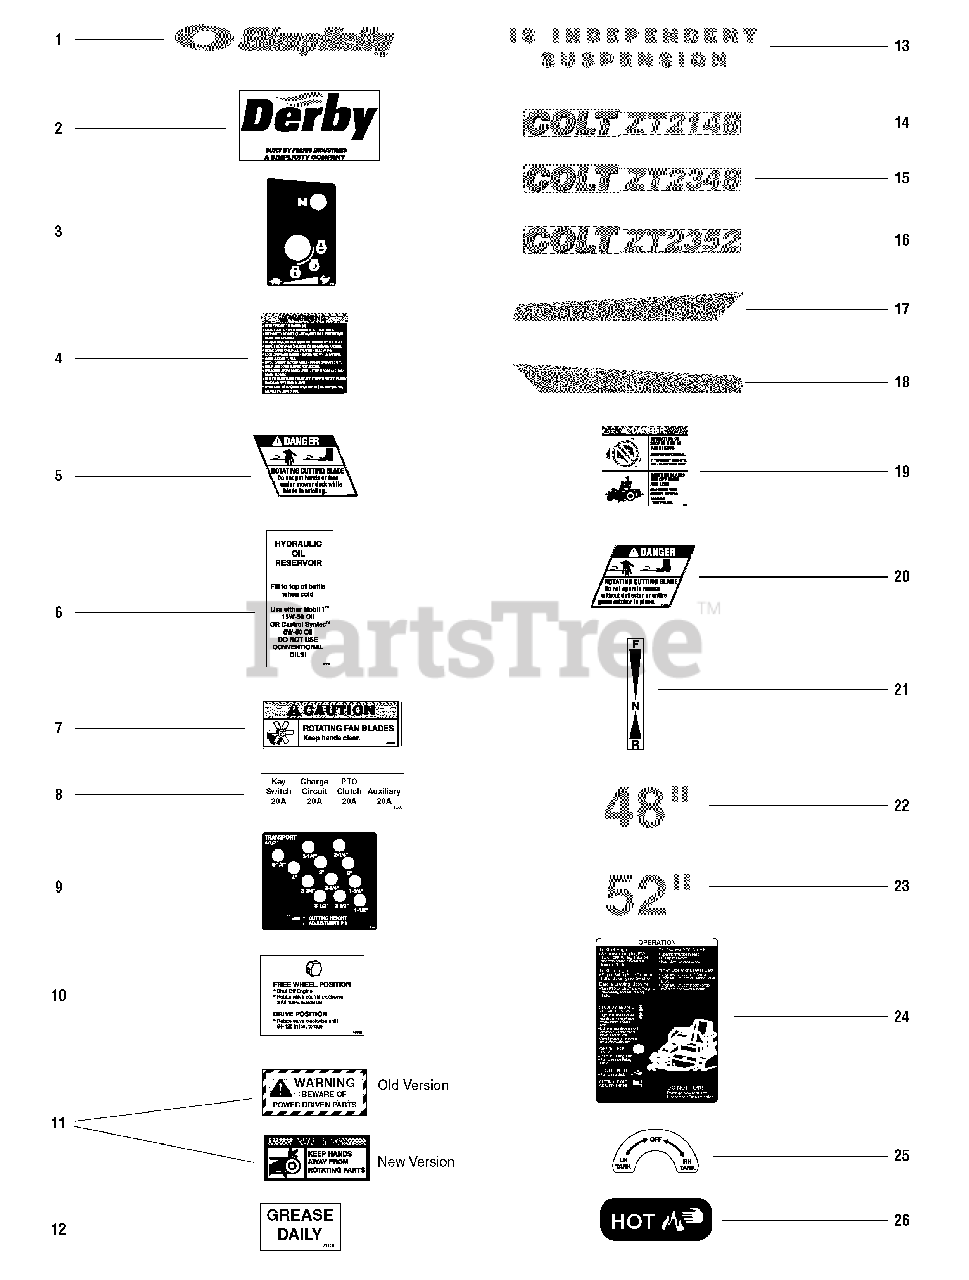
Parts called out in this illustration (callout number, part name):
1	DECAL, Simplicity Logo
2	DECAL, Derby Built By Ferris
3	DECAL, Control Panel
4	DECAL, Warning
5	DECAL, Danger (Hand Under Deck)
6	DECAL, Oil Reservoir
7	DECAL, Caution Fan
8	DECAL, Fuse Location
9	DECAL, Lift Plate
10	DECAL, Hydro Release Valve
11	DECAL, Warning
12	DECAL, Grease Daily
13	DECAL, IS Independent Suspension
14	DECAL, COLT ZT2148
15	DECAL, COLT ZT2348
16	DECAL, COLT ZT2352
17	DECAL, Stripe-LH
18	DECAL, Stripe-RH
19	DECAL, Danger
20	DECAL, Danger (Chute In Place)
21	DECAL, Direction Control
24	DECAL, Operation
25	DECAL, Fuel Valve
